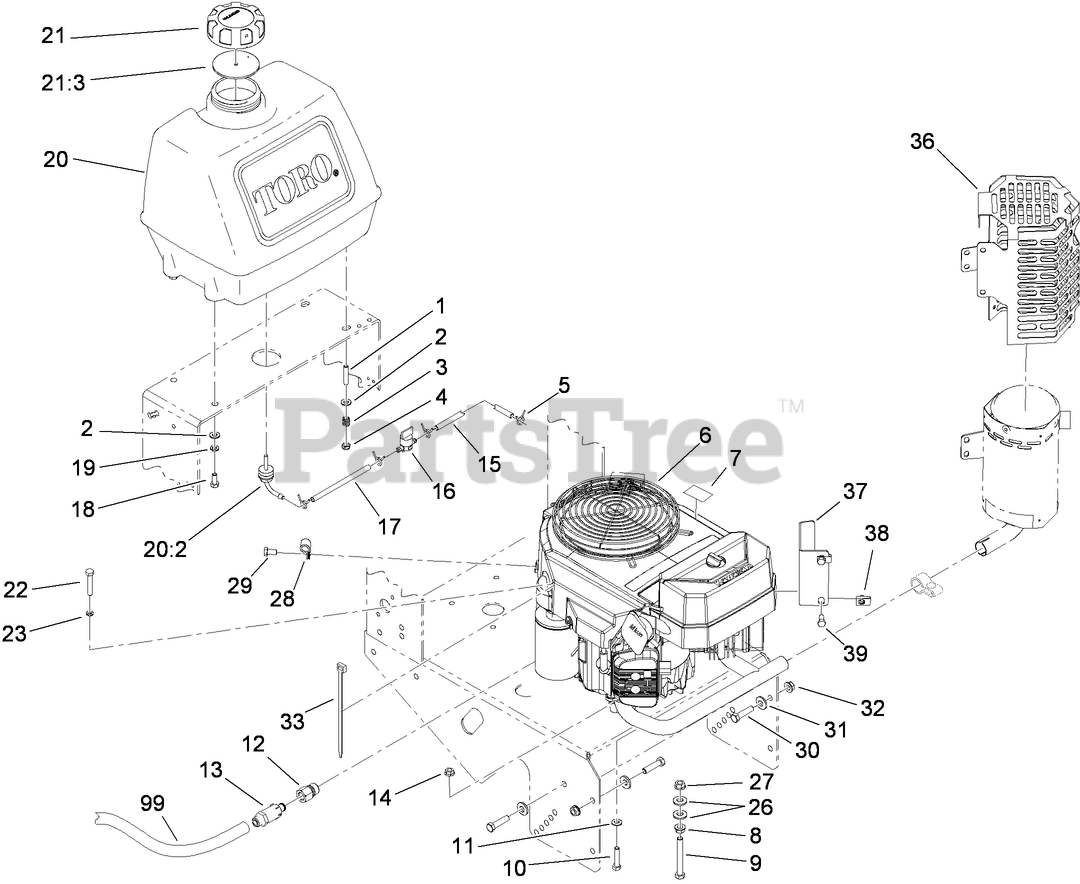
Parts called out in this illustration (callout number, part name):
2	WASHER-PLAIN
3	SPRING-TANK, FUEL
4	NUT-LOCK, NI
7	DECAL-WARNING
8	NUT-HHF, WHIZ
9	SCREW-HH
10	SCREW-HH
11	WASHER-SPRING
12	Adapter
13	VALVE-DRAIN, OIL
14	NUT-HF
15	HOSE-FUEL
16	VALVE-FUEL
17	HOSE-FUEL
18	SCREW-HH
19	WASHER-LOCK
20	FUEL TANK ASM
20:2	FITTING-FUEL, BULKHEAD
21	GAS CAP ASM
21:3	GASKET-CAP, GAS
22	SCREW-HH
23	WASHER-LOCK
26	WASHER-BELLEVILLE
27	NUT-HF
28	Clip-Loom
29	SCREW-HH
30	SCREW-HH
31	WASHER-BELLEVILLE
32	NUT-HHF, WHIZ
33	TIE-PLASTIC
36	MUFFLER SHIELD ASM
37	BRACKET-MUFFLER
38	NUT-U
39	SCREW-HH
99	HOSE-DRAIN, OIL
